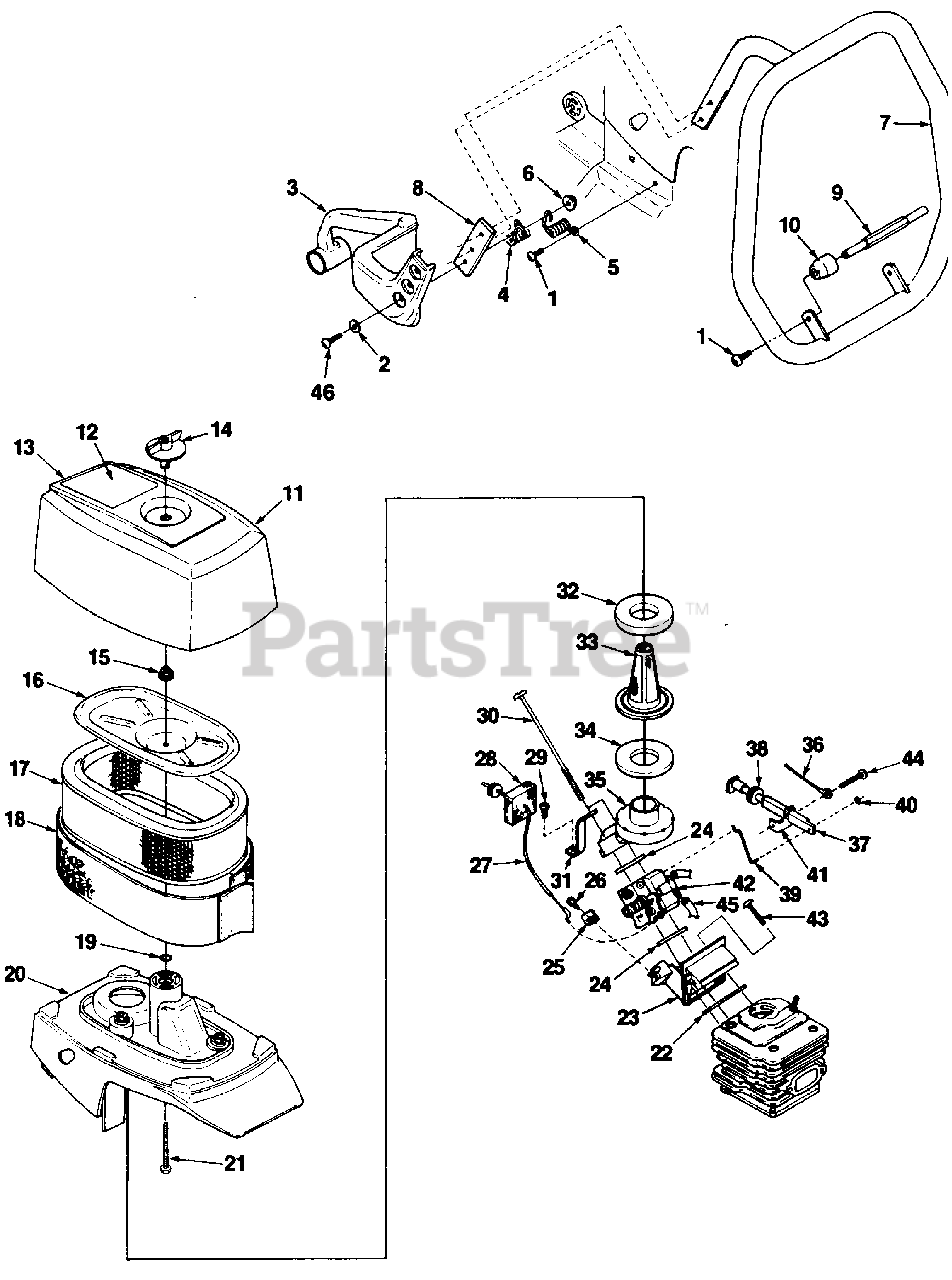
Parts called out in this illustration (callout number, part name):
1	SCREW- Truss hd. (10-24 x 1/2")
3	HANDLE- Rear
4	SPRING- Isolation (small)
5	SPRING- Isolation (large)
6	NUT- Hex
7	HANDLE BAR
8	BRACKET- Handle mounting
9	SPACER
10	ISOLATOR- Vibration
11	COVER- Air filter
12	DECAL- Warning (Eng.)
13	DECAL- Warning (Fre.)
14	KNOB & INSERT
15	NUT- Hex
16	COVER--Air filter element
17	ELEMENT- Air filter
18	PREFILTER- Felt
20	COVER- Cylinder
21	SCREW- Hex cap (10-24 x 13/4")
22	GASKET- Carburetor
23	ADAPTOR- Intake
24	GASKET- Adaptor
25	BRACKET- Cable end
26	SCREW- (6-19 x 1/2")
27	CABLE- Throttle
28	PAD- Foam
29	SCREW- (6-19 x 1/2")
30	SCREW- Truss hd. (8-16 x 31/4")
31	BRACKET- Air intake
32	GASKET- Foam (1/4")
33	FILTER- Screen
34	GASKET- Foam (1/8")
35	ADAPTOR- Air filter
36	GROUND WIRE
37	ROD- Choke
38	GROMMET
39	CHOKE LINK
40	RETAINER- Push On
41	BRACKET- Choke
42	CARBURETOR
43	SCREW- Pan hd. (10-24 x 1")
44	SCREW- (10-24 x 1 1/4")
45	LINE- Pulse (4 3/4")
46	SCREW- Truss Hd. (10-24 x 3/4")
